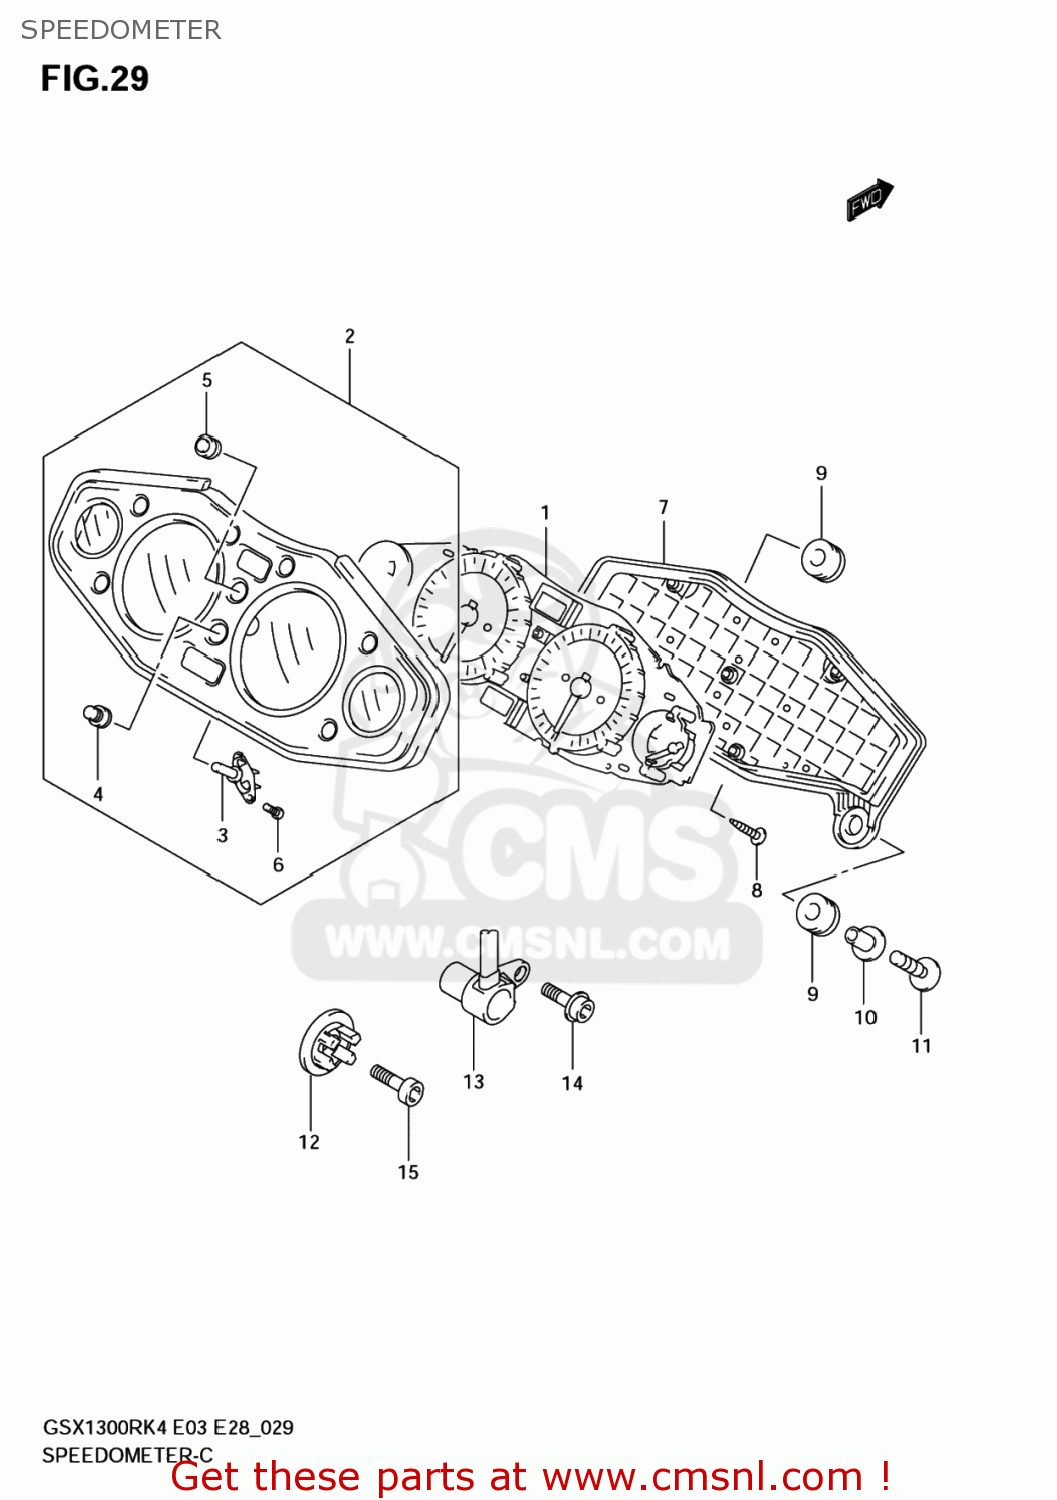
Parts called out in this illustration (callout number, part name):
1	SPEED & TACHOMETER ASSY
2	VISOR ASSY
3	ATTACHMENT,SWITCH
4	SWITCH,GUM
5	SWITCH,LEVER
6	SCREW(3X10)
7	CASE ASSY
8	SCREW
9	CUSHION
10	WASHER
11	BOLT(6X25)
12	ROTOR,SPEED
13	SENSOR,SPEED
14	BOLT
15	BOLT
